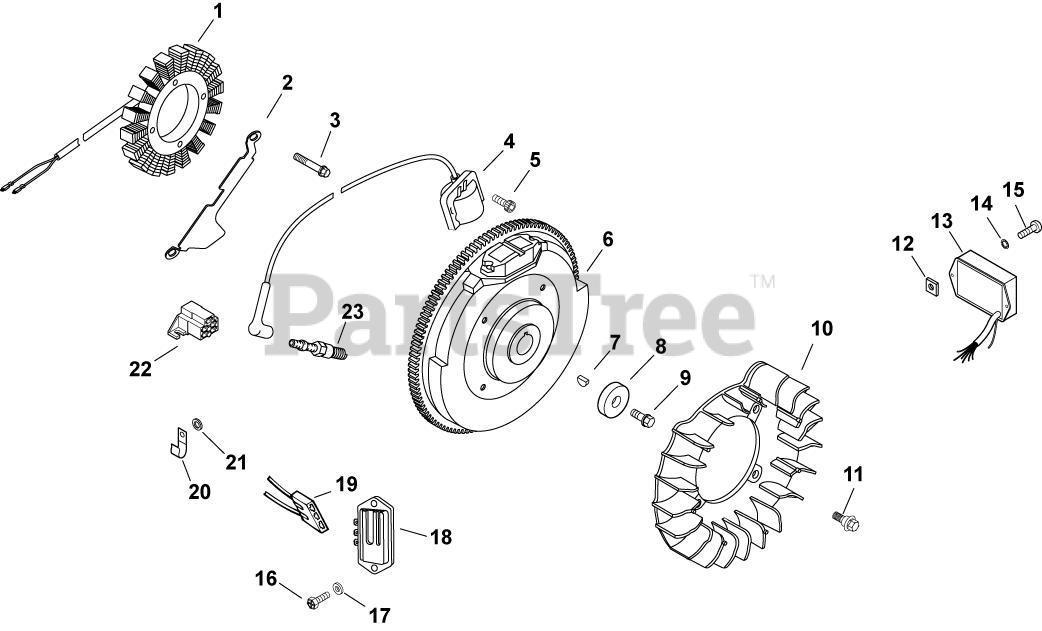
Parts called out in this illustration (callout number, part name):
1	KIT, 15 / 20 AMP STATOR
2	BRACKET, STATOR WIRE
3	SCREW, M5X0.8X25 - (#25086402S)
4	MODULE, IGNITION
5	SCREW, SKT THD FRM M5X0.8X25
6	FLYWHEEL, PAINTED-USE 24 025 57-S
7	KEY, 3/16" X 5/8"
8	WASHER, FLAT 13/32"
9	SCREW, FLG M10X1.5X45 - (#25086361S)
10	FAN (WITH HOLE)-USE 24 157 16-S
11	BOLT, SHOULDER
12	NUT, PLASTIC
13	MODULE, SPEED ADVANCE-DISCONTINUED SEE PB265
14	WASHER, INT TOOTH LOCK 1/4"
15	SCREW, PHL HD #11-16X1/2"
16	SCREW, PHL HD #11-16X7/8"
17	WASHER, FLAT 3/16"
18	REG/RECT-15 AMP (KM)-USE 41 403 10-S
19	CONNECTOR, BODY (KM)-USE 25 155 41-S
20	CLIP, CABLE
21	WASHER, FLAT 1/4" (O.D. 1/2")
22	CONNECTOR
23	PLUG, SPARK (STD)
